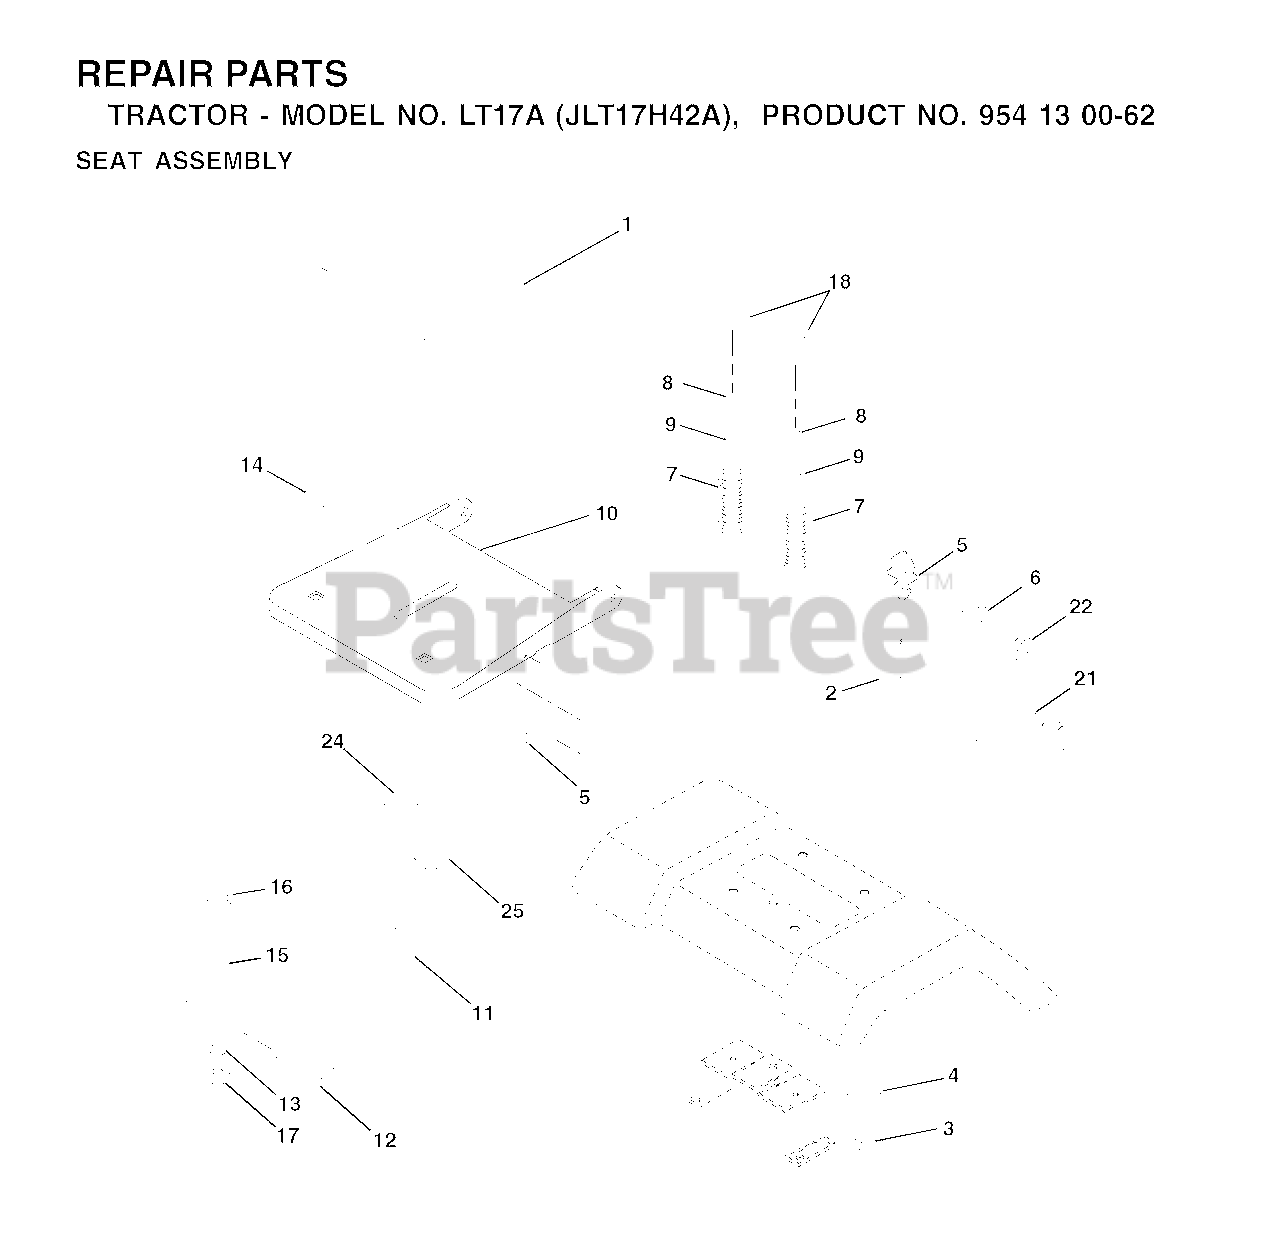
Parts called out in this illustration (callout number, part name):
2	SEAT PIVOT BRKT
4	WASHER PM
5	PUSH CLIP
6	NUT
7	SPRING COMPRESSION
8	SCREW 3/8-16X1
9	WASHER
10	PAN SEAT
11	KNOB.SEAT.ADJ.WINGNUT
12	BRKT SWITCH
14	BOLT.ROUND.HEAD.SQUARE.NECK
15	SPACER SPLIT
16	SPRING COMPRESSED
17	NUT T
18	CAP SPRING
21	BOLT.SHOULDER.5/16-18
22	NUT.71038.31-18.HEX.NYLOCK
25	BOLT,SHOULD
